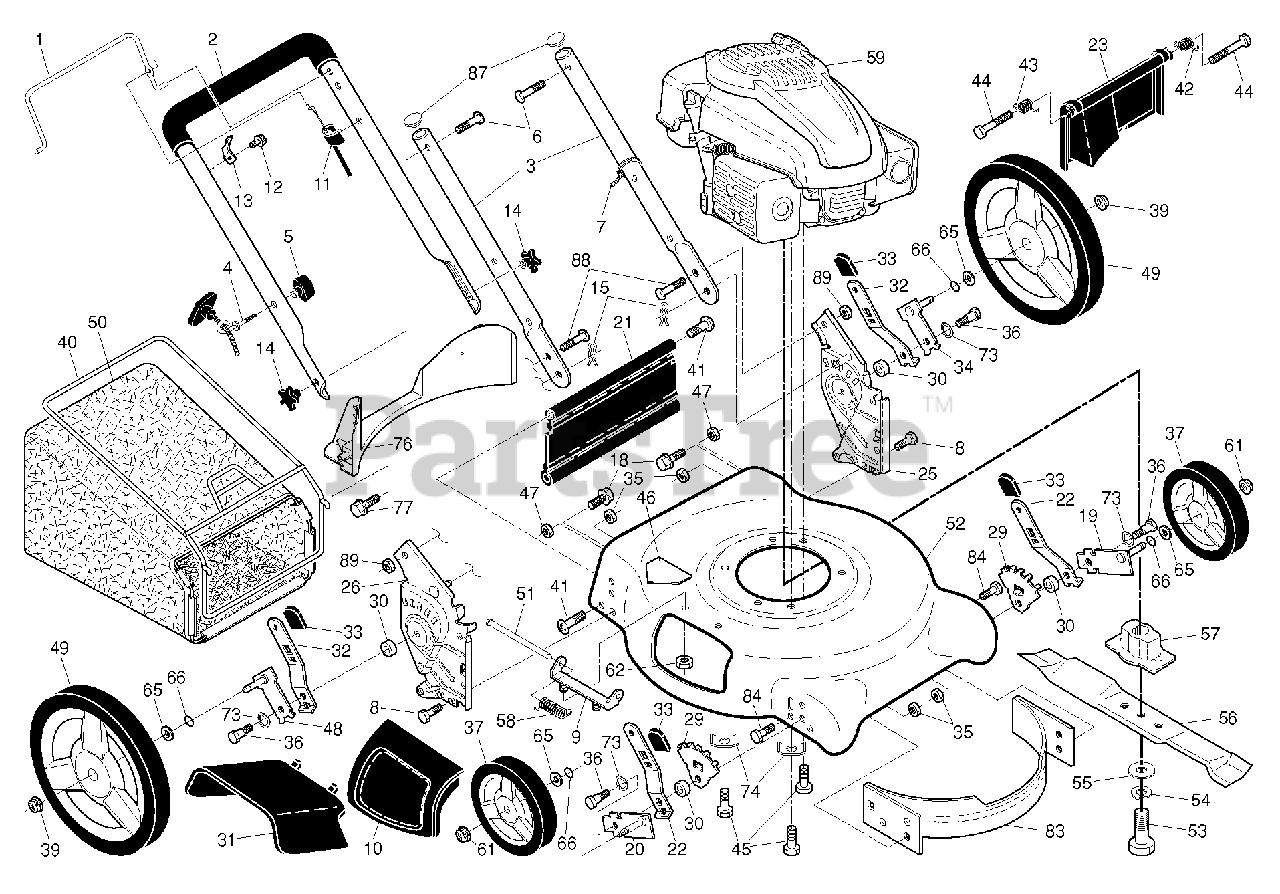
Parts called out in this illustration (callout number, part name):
1	CONTROL BAR
2	HANDLE.UPPER.WITH.GRIP
3	HANDLE.LOWER.DOME.BT.GREY
4	GUIDE.ROPE.BLK.ZINC.CHROM
5	T-KNOB.NEW ROPE GUIDE
6	BOLT, HANDLE 5/16-18X1.75
7	TIE GUIDE
8	BOLT
9	BRACKET.ASM.HOUSING.EZ.MUL
10	DOOR.MULCH.21".REAR.PUSH.GRAY
11	CABLE.MZR.RATO.22"LOW.
13	BRACKET.UPSTOP.RT
14	KNOB.HANDLE.PLASTIC.STAR.BLACK
15	HAIRPIN COTTER
18	SCREW 1/4X20
19	AXLE ARM ASSY FRONT LH
20	AXLE ARM ASSY FRONT RH
21	RP_KIT.SKIRT.21 DOMED.W/LIP
22	SELECTOR SPRING, FRONT
23	DOOR.REAR.21.DOMED.498
25	BRACKET.ASM.HAND.HW.21.LT.GREY
26	BRACKET.ASM.HAND.HW.21.RT.498
29	WHEEL ADJ BRACKET FRONT
30	SPACER.HEIGHT.ADJUSTER(2 2)3 2
31	DEFLECTOR.CLIPPING.21.GREY
32	SPRING.SEL.22.ECON.HI-WHL.RATO
33	SELECTOR KNOB
34	AXLE ARM ASSY REAR LH
35	NUT.FLANGE.HEX.5/16X18.BLACK
36	SHOULDER BOLT 5/16-18
37	WHEEL & TIRES ASSY, FRONT
39	NUT.HEX.FLANGE.3/8-16.LOCKNUT
40	FRAME.BAG.21.REAR.DOMED.PUSH
41	SCREW.1/4-20X21/4.HEX.
42	SPRING.LH.22.REAR.DOOR.EZ.EMPT
43	SPRING.RH.22.REAR.DOOR.EZ.
45	BOLT 3/8-16X1-1/8
46	DANGER DECAL
47	NUT.LOCK.5/16-18
48	AXLE ARM ASSY REAR RH
49	WHEEL.12 X 1.75 CFH3SPK.RAD3
50	GBAG.23230247.SILVER.HUSQ.BLUE
51	ROD.HINGE.COMBI-C
52	HOUSING.21.M/C.DOME.ORANGE
53	SCREW, HEX HD 3/8-24 X 1-3/8
54	LOCKWASHER
55	WASHER,HARDEN
56	BLADE.21.PUSH/RWGD/FWGD
57	ADAPTER.BLADE.W/KEY.25MM.CE
58	TORSION SPRING
61	NUT.HEX.FLANGE.3/8-16.LO(3 2)
62	LOCKNUT.NYLOC.1/4-20
66	O-RING..070X.487.NEOPRENE
73	WASHER.CURVED.CYLINDRICAL
74	WASHER.ENGINE.BZP
76	BAFFLE.REAR.PLASTIC.21.RD.ECON
77	SCREW.HX.13X.750
83	BAFFLE.FRONT.21.DOME.US
84	BOLT.5/16HEX.WHS.HD
87	PLUG.PLASTIC.7/8".14-20.GAUGE
88	BOLT
89	LOCKNUT-FLANGE 5/16-18
